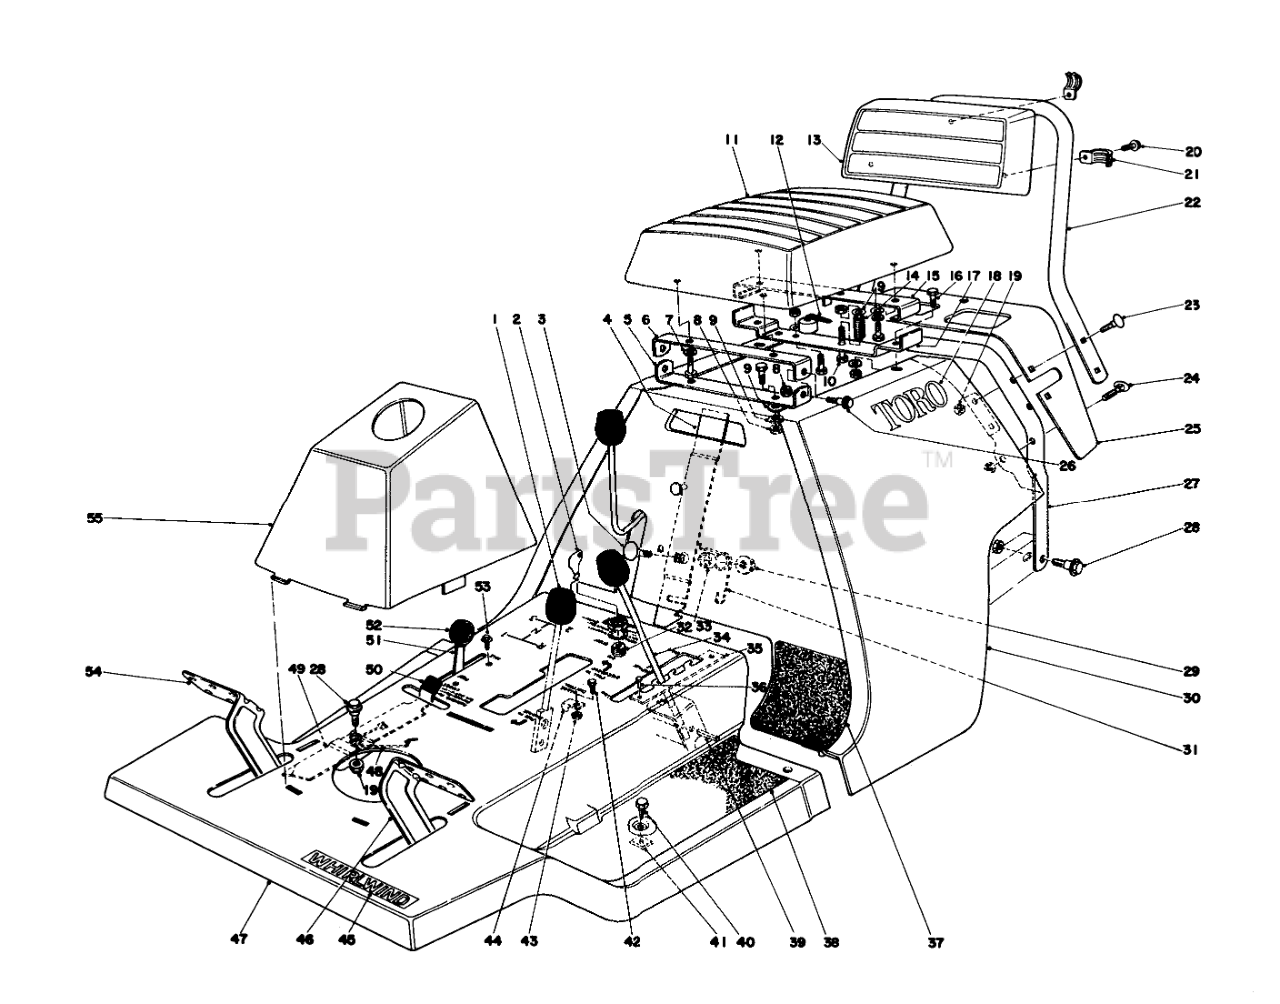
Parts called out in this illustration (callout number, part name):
2	Key
3	BOLT-CARR
4	Handle Latch
5	Seat Pivot Brkt-Lower
6	Seat Pivot Brkt-Upper
7	WASHER-LOCK
9	WASHER-FLAT
10	SCREW-HH
12	SEAT SWITCH
13	Backrest
14	Spring
15	Rear Support Seat
16	SCREW-HH
17	Seat Support Rear Lower
18	TORO LOGO DECAL
19	NUT-LOCK, CONE
20	SCREW-HHF
21	CLAMP-CONDUIT
22	Handle Upper
23	SCREW-CARR
24	HANDLE SCREW
25	Extension Rear Body
26	SCREW-SHOULDER
27	Handle Lower
28	SCREW-SHOULDER
29	NUT-HF
30	Rear Body
31	Latch Return Spring
32	STARTER SWITCH
33	Spacer
34	Height of Cut Lever
35	Height Adjustment Plate
37	Heel Pad-LH.
38	Foot Tread LH.
39	PIN-SPECIAL
40	SCREW-HH
41	NUT-TINNERMAN
43	NUT-KEPS
44	CABLE CLAMP
45	WW DECAL
46	Clutch Pedal
47	Body Front (Incl. Ref. #35 & 36)
48	SPRING-PARKING BRAKE
49	Parking Brake
50	TIP-PARKING BRAKE
51	Throttle Control (Incl. Ref #52)
53	8X1/2 SELF TAP SCREW
54	Brake Pedal
55	Tower
